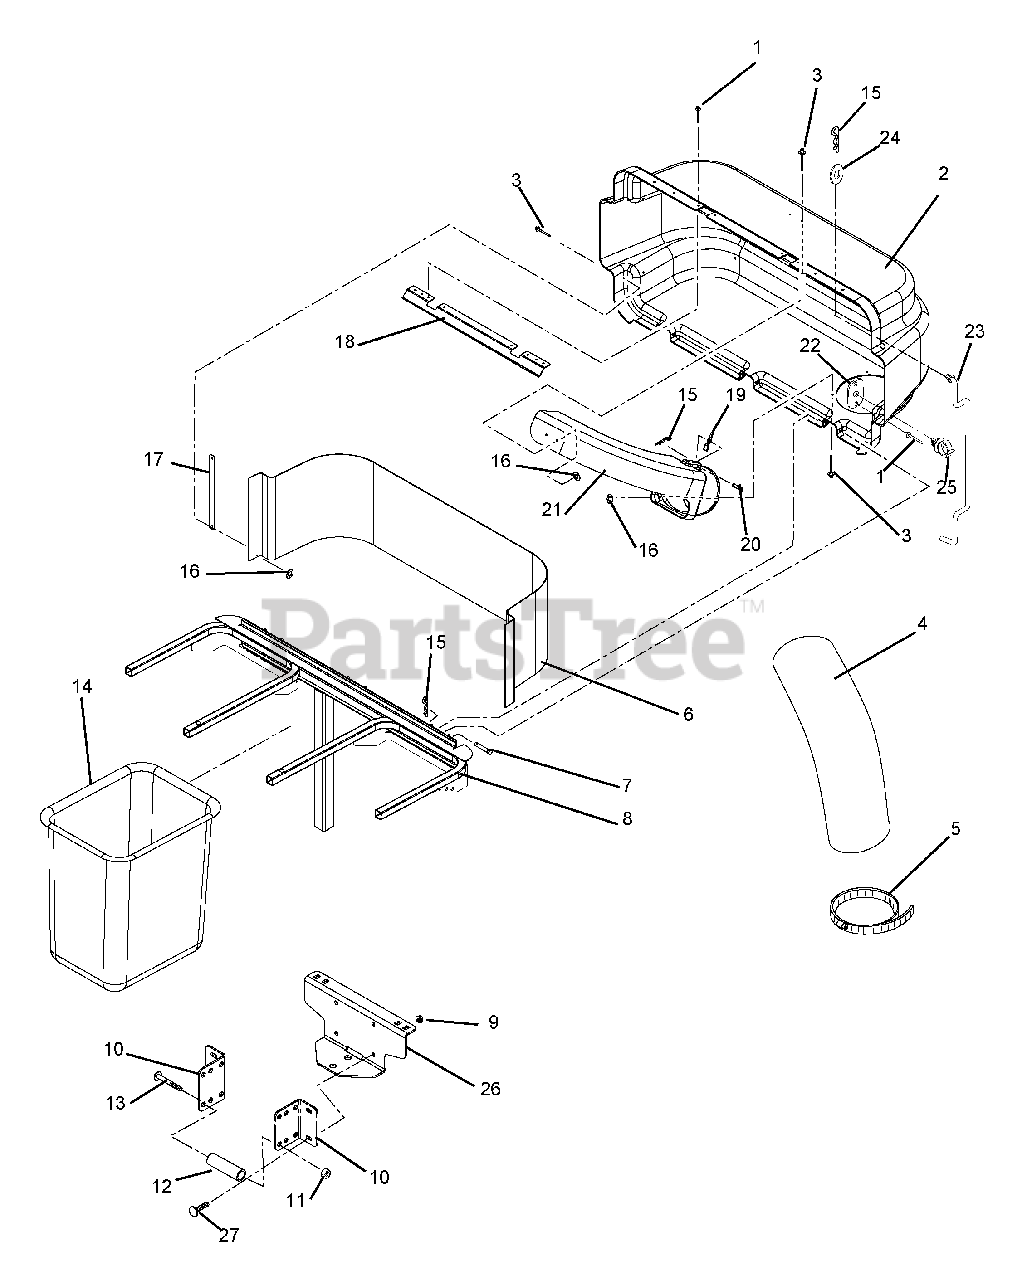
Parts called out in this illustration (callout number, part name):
1	Rivet-Pop .187 x .402
2	Cover, Bagger with Decal
3	Rivet-Pop .187 x .375
4	Hose 7 x 45
5	Clamp, 7" Tool-less Hose
6	Screen, Bagger
7	Pin-Clevis .368/.373 x 3.25
8	Weldment, Bagger Frame
9	Nut-Locking-Top-Flange .38-16
10	Bracket, Bagger Mount
11	Nut-Locking-Top-Flange .50-13
12	Spacer, Pivot
13	Bolt-Hex .50-13 x 3.00 Grade 5
14	Grass Bagger Basket
15	Pin-Hair
16	Washer-Flat-Steel .219 x .50 x .049
17	Strap, Cover
18	Latch, Cover
19	Indicator, Flow
20	Pin-Clevis .31 x 2.62 Grade 5
21	Boot, Upper
22	Plate, Rod Clip
23	Prop-Rod, Bagger
24	Washer-Flat-Steel .046 x .812 x .065
25	Clip .38
26	Trailer Hitch with Decal
27	Bolt, Round Head Square Neck .38-16 x .75 Grade 5
